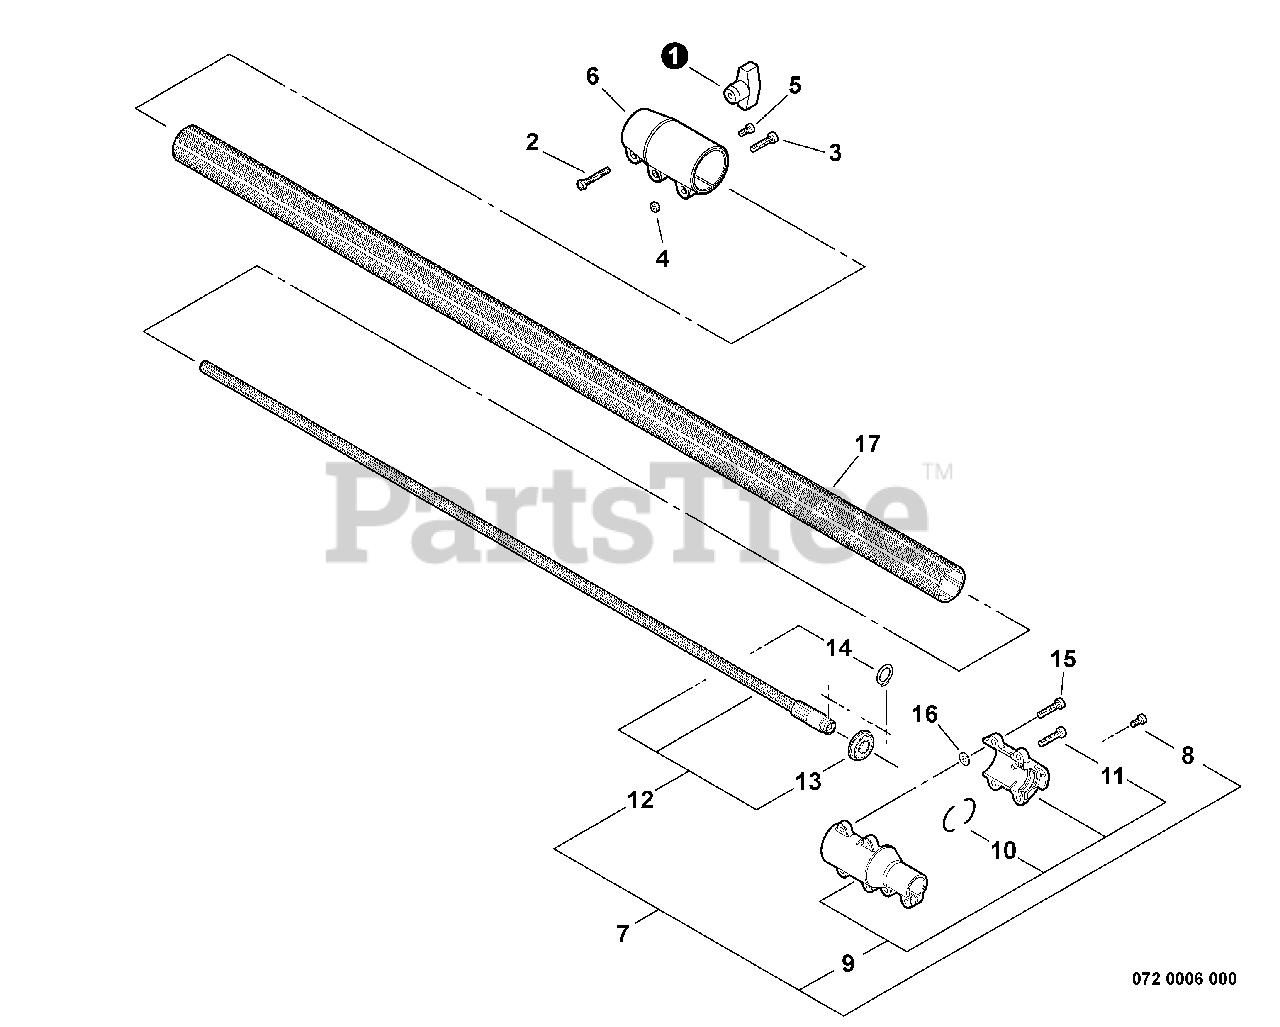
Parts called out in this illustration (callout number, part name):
1	THUMBSCREW
2	BOLT - 6X25
3	SCREW - 5X20
5	SCREW - 5X12
6	COUPLING
7	DRIVESHAFT ASSY
8	SCREW - 5X14
9	COUPLING ASSY
10	CUSHION
11	SCREW - 5X20
12	DRIVESHAFT ASSY - LOWER
13	BEARING, BALL - 6002
14	RING, RETAINING
15	SCREW - 5X20
16	WASHER - 5
17	PIPE, MAIN - ORANGE
